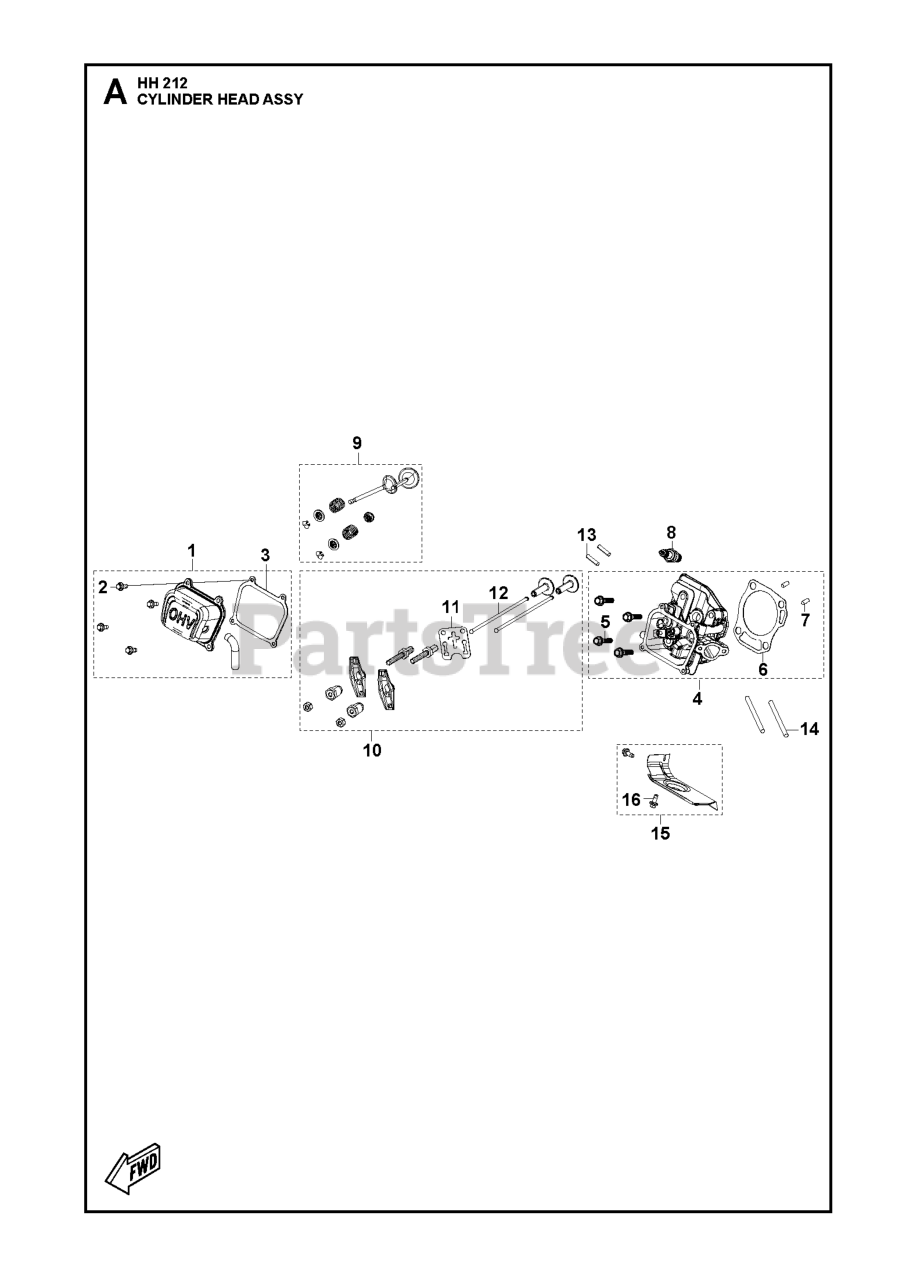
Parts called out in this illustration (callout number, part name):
1	CYLINDER COVER ASSY CYLINDER H
2	BOLT
3	GASKET CYLINDER HEAD COVER GAS
4	CYLINDER HEAD KIT
6	GASKET CYLINDER HEAD GASKET
7	PIN LOCATION PIN
8	SPARK PLUG HQT-7 RESISTOR
10	PUSH ROD ROCKER ARM KIT
11	PLATE PUSH ROD GUIDE PLATE
12	PUSH ROD PUSH ROD SET
15	DEFLECTOR AIR DEFLECTOR KIT
16	BOLT
